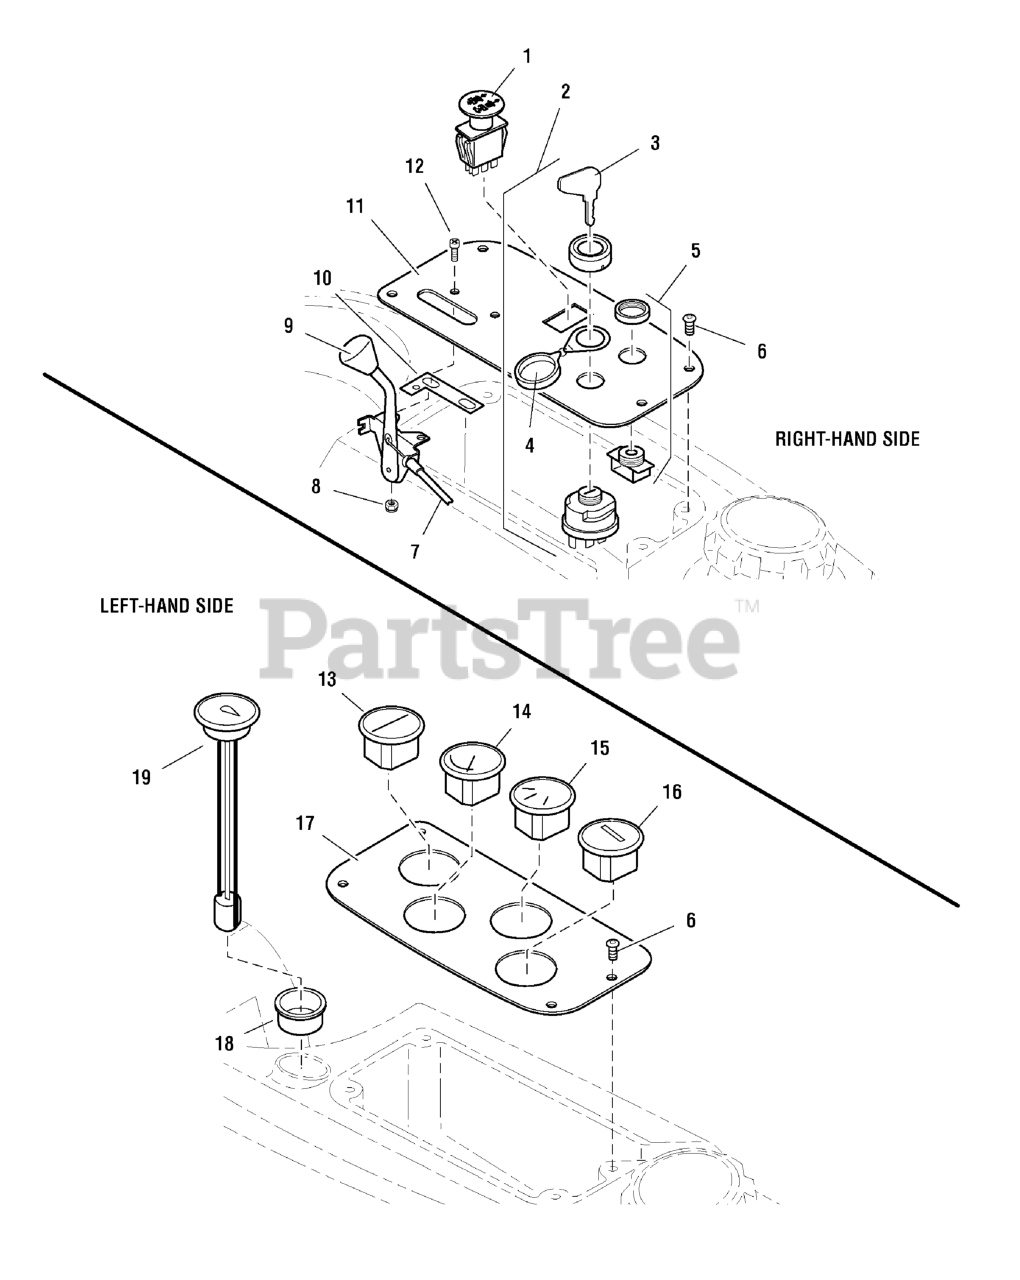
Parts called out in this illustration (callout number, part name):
1	SWITCH, BLADE ENGAGEMENT
2	SWITCH, Ignition, Complete
3	KEY, Ignition
4	COVER PLATE
5	INDICATOR, Glow Plug
6	SCREW, Allen Head, 1/4-20 x 1/2
7	CABLE, Throttle Control, 47-1/2"
8	NUT, #10-24 Hex Nylon Lock
9	HANDLE, THROTTLE CONTROL
9	THROTTLE CONTROL HANDLE/KNOB
10	THROTTLE STOP PLATE
11	CONTROL PANEL-RH
12	SCREW, #10-24 x 3/4
13	GAUGE, Warning, Oil/Temp
14	GAUGE, Water Temperature
15	GAUGE, Voltmeter
16	HOUR METER
17	PANEL, GAUGE CLUSTER (4)
18	GROMMET
19	GAUGE, FUEL, 12
